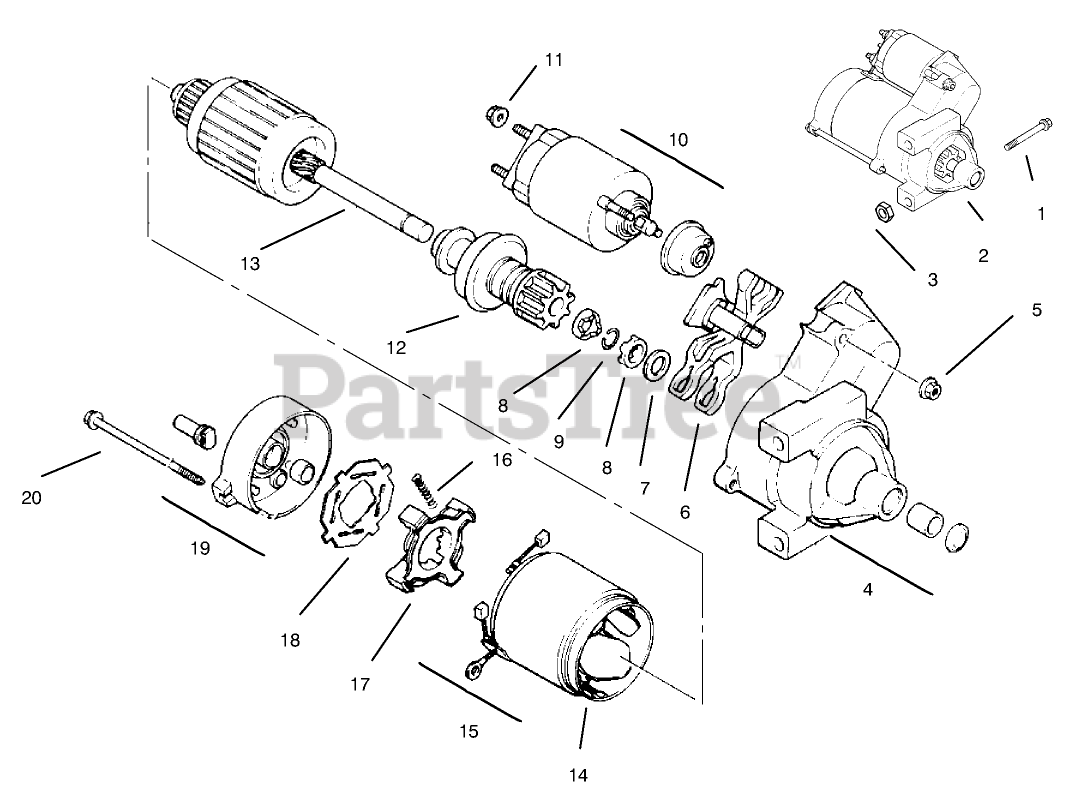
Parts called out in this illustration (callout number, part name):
1	Screw
2	Starter-Solenoid Shift (Incl. Ref. # 4-20)
3	Nut
4	Cap-Drive End
5	Nut
6	Lever Starter Drive
7	Washer
8	Nut
9	Ring-Retainer
10	Solenoid
11	Nut
12	Drive Pinion
13	Armature
14	Frame
15	Kit-Brush (Incl. Ref. # 16)
16	Spring Brush
17	Holder-Brush
18	Insulator
19	Cap-Commutator End
20	Bolt
